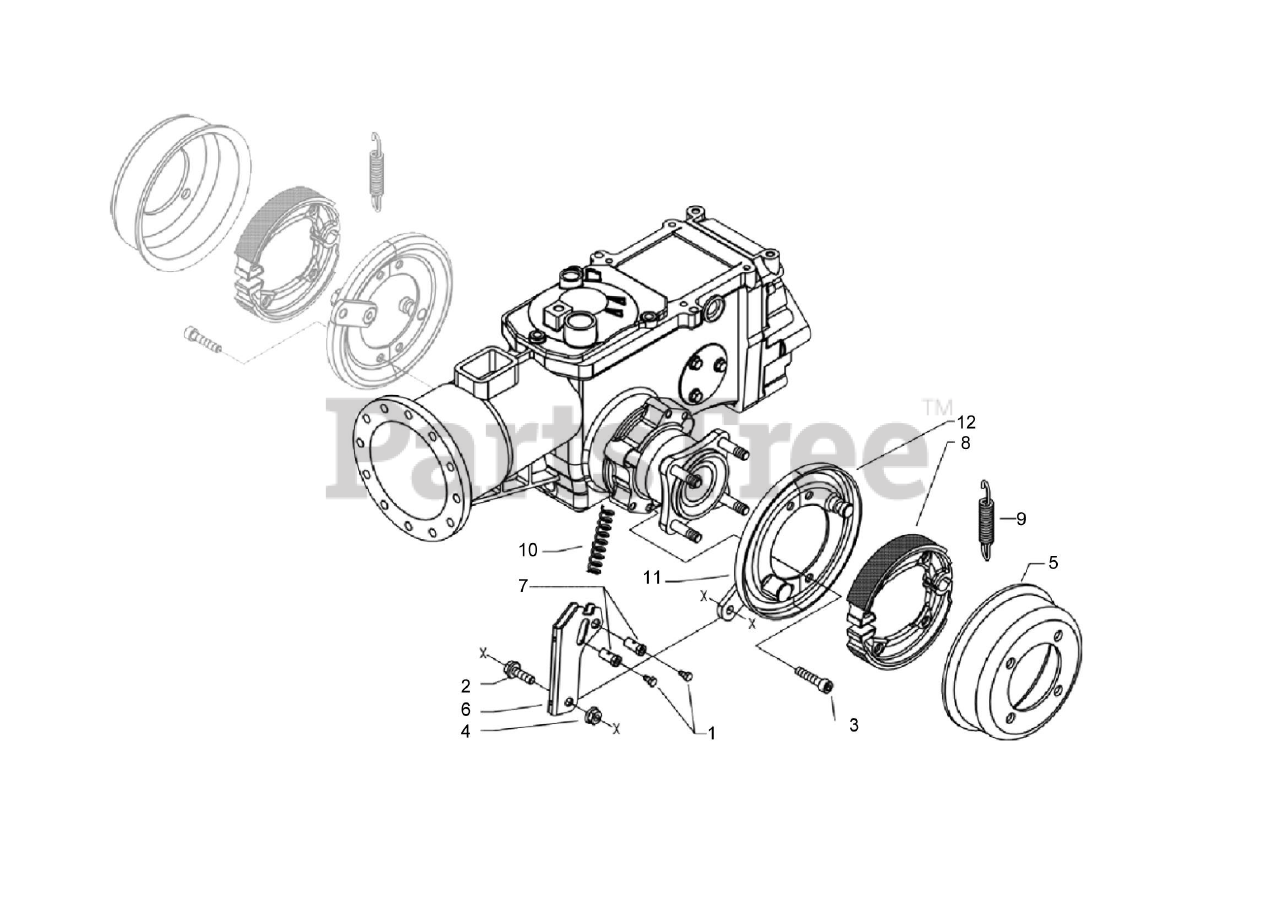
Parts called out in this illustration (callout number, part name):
1	CAPSCREW M6X16
2	SCREW TE M8X25
3	CAPSCREW M8X25
4	LOCKNUT M8 FLANGED
5	BRAKE DRUM
7	SCREW, CLAMPING
8	SHOE
9	SPRING
10	SPRING, STEERING COLUMN
11	LEVER,HALF DISC COMPLETE
12	PIN, HALF DISC COMPLETE
